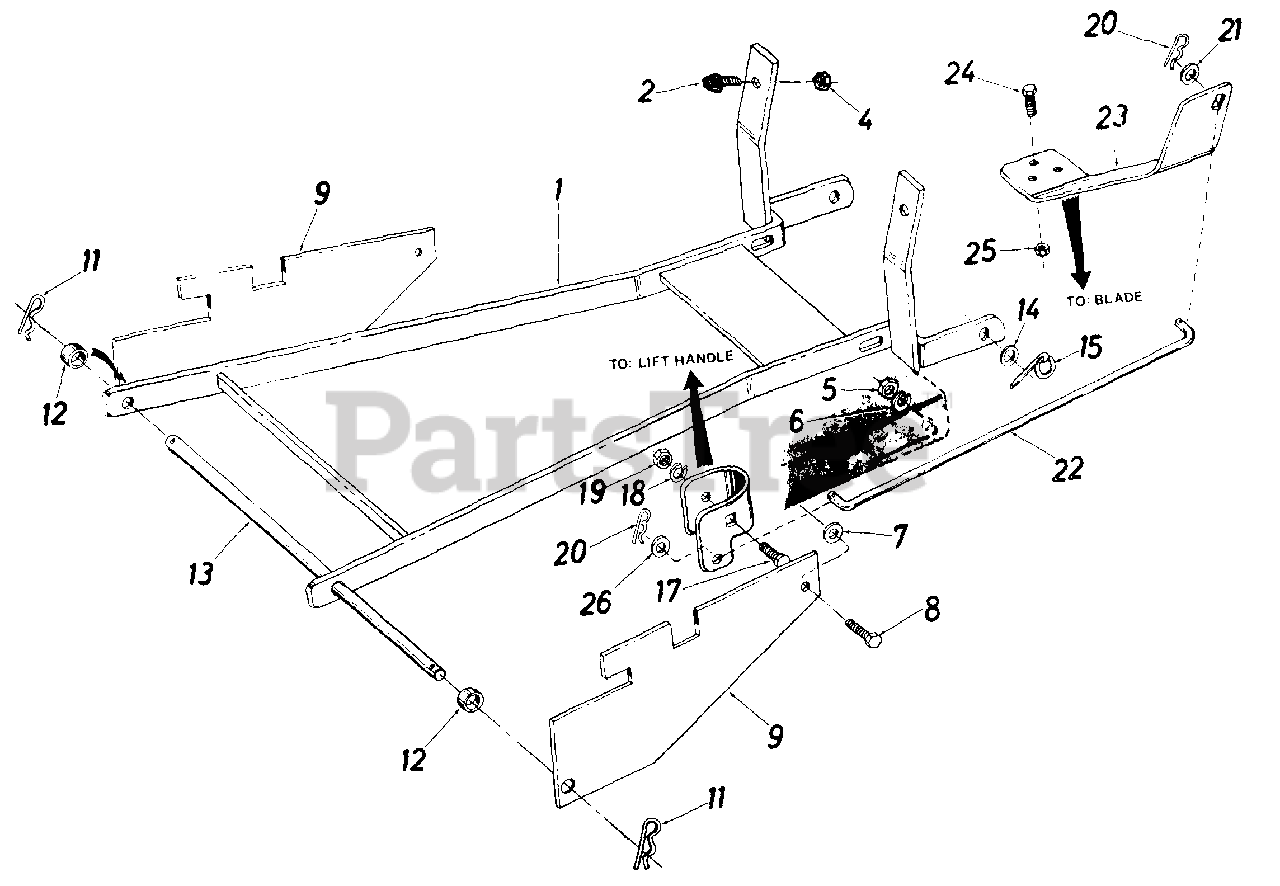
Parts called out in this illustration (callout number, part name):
1	Blade Sub Frame Ass'y.
2	Rubber Bumper
4	Hex Jam Nut 5/16-24 Grade 5
5	Hex Cent. L-Nut 3/8-16 Grade 5
6	L-Wash 3/8
7	Fl-Wash. .390 I.D. x 1.50 O.D. x .134
8	Hex Scr. 3/8-16 x 1-1/4 Lg. Grade 5
9	Side Plate
11	Int. Cotter Pin
12	Spacer .88 I.D. x 1-1/8 O.D. x .69 Lg.
14	Fl-Wash. .783 I.D. x 1.59 O.D. x .06
15	Klik Pin
17	Carriage Bolt 3/8-16 x 1.75" Lg.
18	L.-Wash. 3/8" I.D.
19	Hex Cent. L.-Nut 3/8-16 Thd.
20	Internal Cotter Pin
21	Fl.-Wash. .656 I.D. x 1.312 O.D. x .070
24	Hex Bolt 1/2-13 x 1.25" Lg. Grade 5
26	Hex Nut 1/2-13 Thd.
26	Fl.-Wash. .531 I.D. x .875 O.D. x .054
